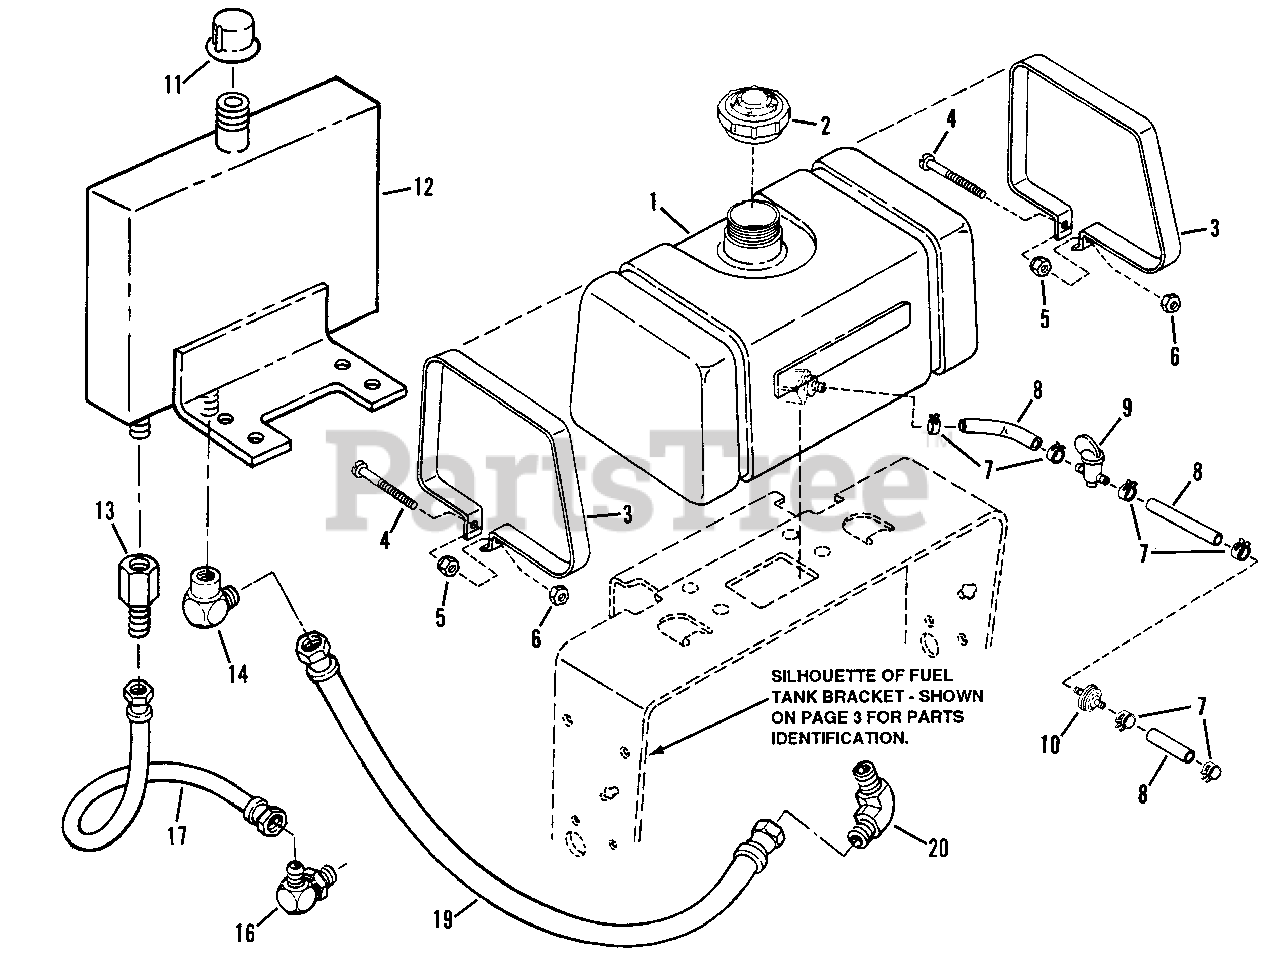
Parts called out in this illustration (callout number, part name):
1	TANK, Fuel
2	CAP, Fuel
3	STRAP, Fuel Tank
4	SCREW, #10 - 24x 2" Machine Head
5	NUT, #10 - 24 KEPS
6	NUT, #10 - 24 Nyloc
7	CLAMP, Fuel Hose
8	HOSE, Fuel 7"
9	VALVE, Fuel Shut-off
10	FILTER, Fuel In-Line
11	CAP, Hydraulic
12	TANK, Reservoir
13	FITTING, Straight
14	FITTING, 90 Degree
16	FITTING, 90 Degree
17	HOSE, 9" Hydraulic
19	HOSE, 12" Hydraulic
20	FITTING, 90 Degree
